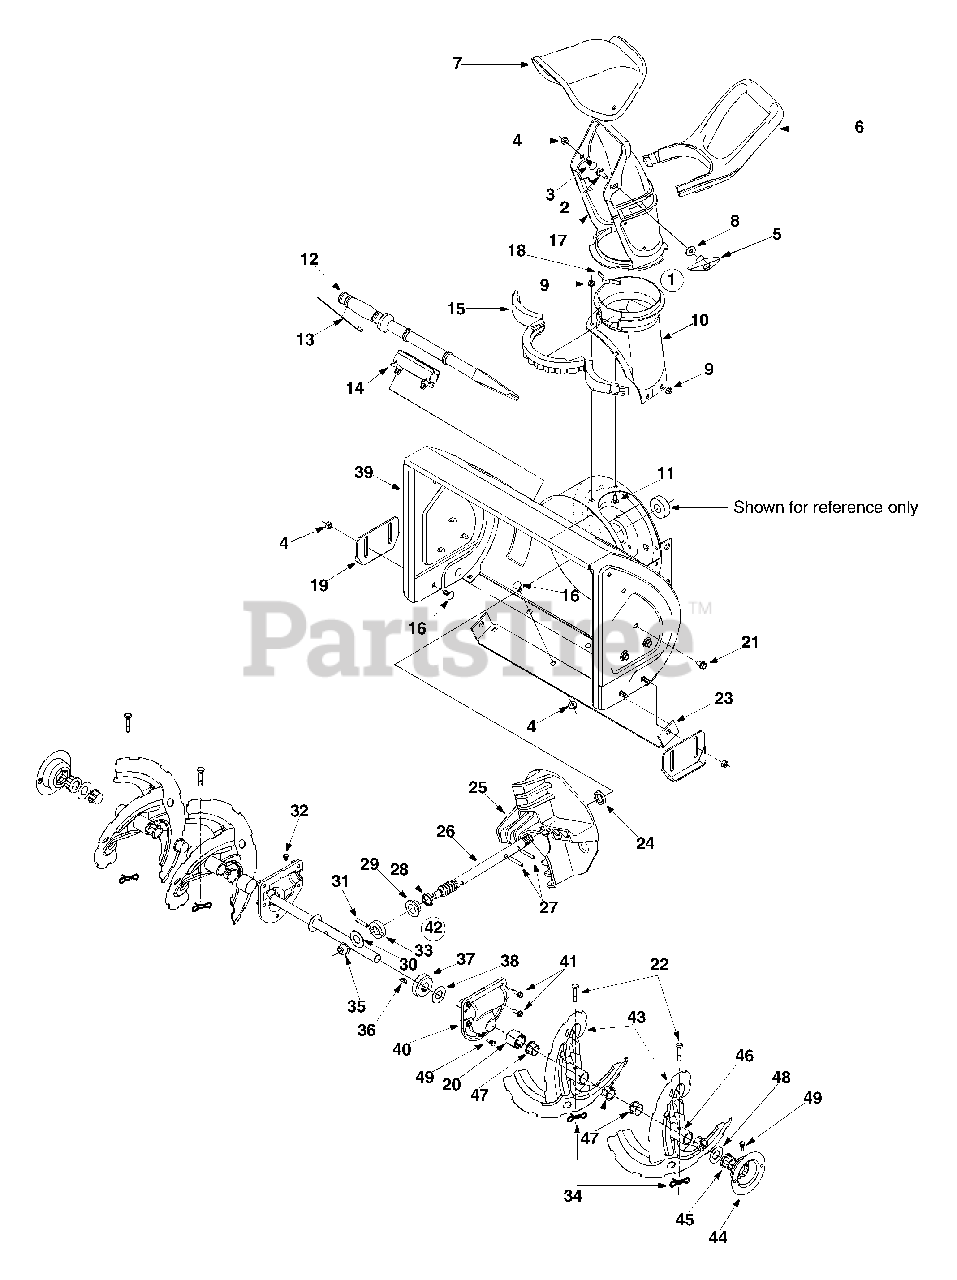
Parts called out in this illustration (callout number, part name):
1	Chute Assembly
2	Carriage Bolt 5/16-18 x 1.0"
3	Carriage Bolt 5/16-18 x 0.750"
4	Flange Lock Nut, 5/16-18
5	Chute Knob Assembly
6	Chute Handle
7	Upper Chute
9	Flange Lock Nut, 1/4-20
10	Chute Adapter
11	Carriage Screw 1/4-20 x 0.62"
12	Clean-out Tool
13	Cable Tie
14	Clean-out Tool Mount
15	Lower Chute Ring
16	Carriage Bolt 5/16-18 x 0.75"
17	Lower Chute
18	Chute Adjuster Spring
19	Screw, Carriage 5/16-18 x .750
19	Nut, Nylon Lock 5/16-18
19	Washer, Flat .349 x .879 x .063
19	Skid Shoe, Polymer Small
19	Standard Polymer Reversible Shoe Kit
19	Screw, Carriage 5/16-18 x 1.00
20	Spacer, 1.25OD x .75ID x 1.00Lg.
21	AB Screw 5/16-12
22	Shear Pin,.25 x 1.50
24	Spacer
25	Impeller
26	Worm Shaft
27	Spiral Pin
29	Flange Bearing
30	Flat Washer, .51 x 1.12 x.06
31	Spiral Pin
33	Thrust Collar
34	Bow Tie Cotter Pin
35	Flange Bearing
36	Key
37	Worm Gear 20T
38	Flat Washer
40	Reducer Housing Assembly RH
41	TT Screw 1/4-20x 0.75"
42	Auger Gearbox Assembly
45	Hex Flange Bearing
46	Auger Axle, 24"
47	Flange Bushing
48	Flat Washer
49	Lube Fitting
